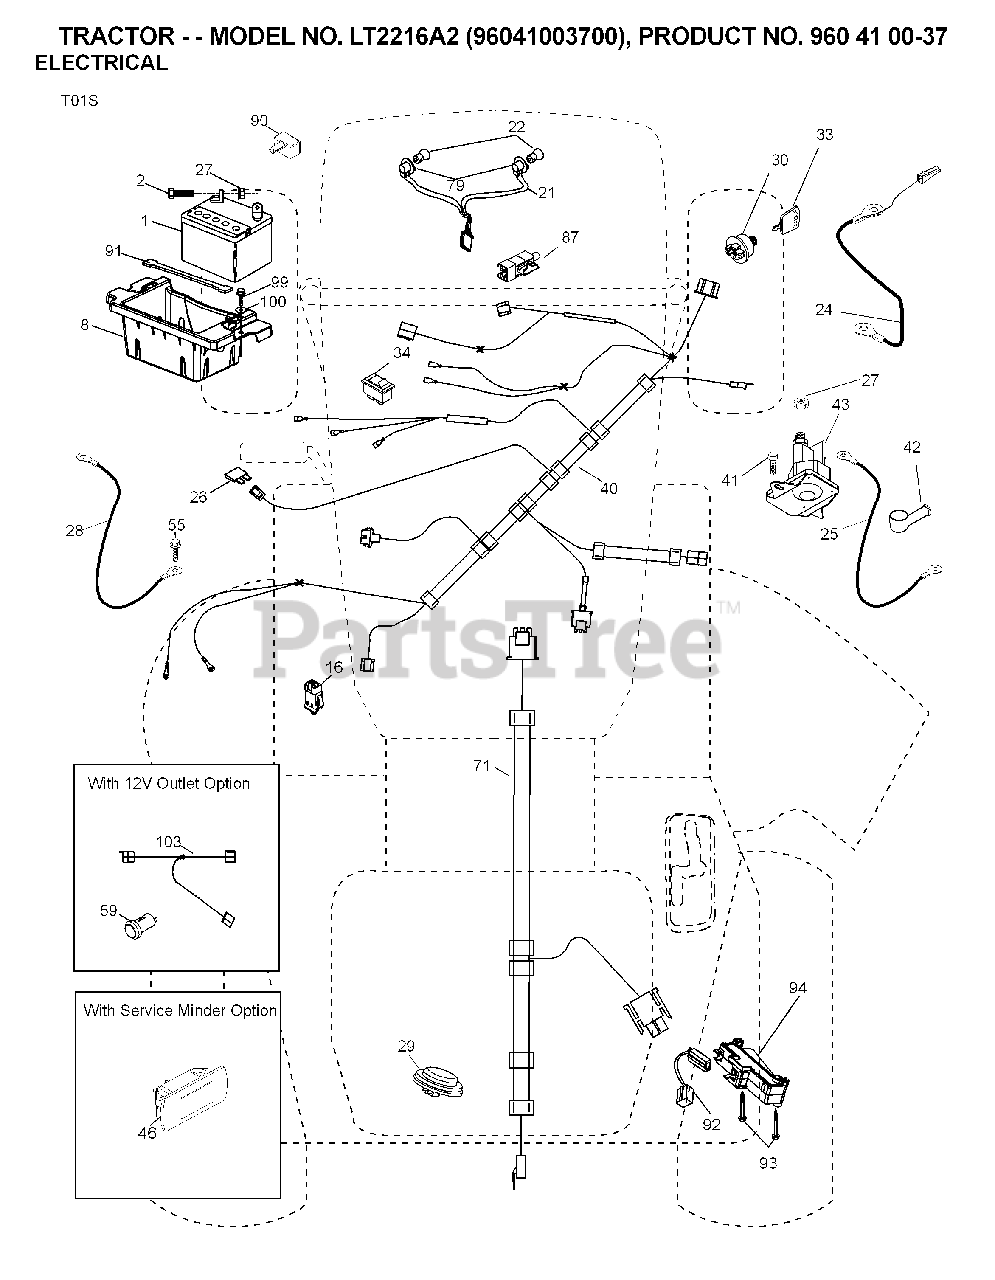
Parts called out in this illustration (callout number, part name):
1	BATTERY 12V .35 AMP
8	BOX.BATTERY.MOUNT.FRONT.LT
16	SWITCH INTERLOOK PUSH-IN
21	HARNESS ASSY LIGHT
22	LIGHTBULB
24	CABLE.BATT.POS.WIRE.TG.DA SOL
25	CABLE.STARTER.6GA.RED.
26	FUSE 20AMP
27	NUT
28	CABLE GROUND 6 GA 21" 90T BLK
29	SWITCH.SEAT.DELTA.OPC.
30	SWITCH.IGN.DELTA.W.LGH.ROS
33	KEY MLD GEN DELTA
34	SWITCH LT
40	HARNESS IGN. DASH
41	SCREW
42	TERMINAL COVER
43	SOLENOID.W/BRASS.PLUNG
46	GUAGE.SRVCMNDR.HRMTR.
55	SCREW 5/16"
71	HARNESS-CHASSIS SUB
79	BULB HOLDER ASM.
87	SWITCH.INTRLCK.CLUTCH.
90	COVER.TERMINAL.BATTERY
91	STRAP, BATTERY MOUNT
92	HARNESS.PIGTAIL.CONSLE
93	SCREW.PLASTITE
94	MODULE.REVERSE.ROS
99	SCREW HEXWSHR 1/4-20X3/4
100	WASHER
